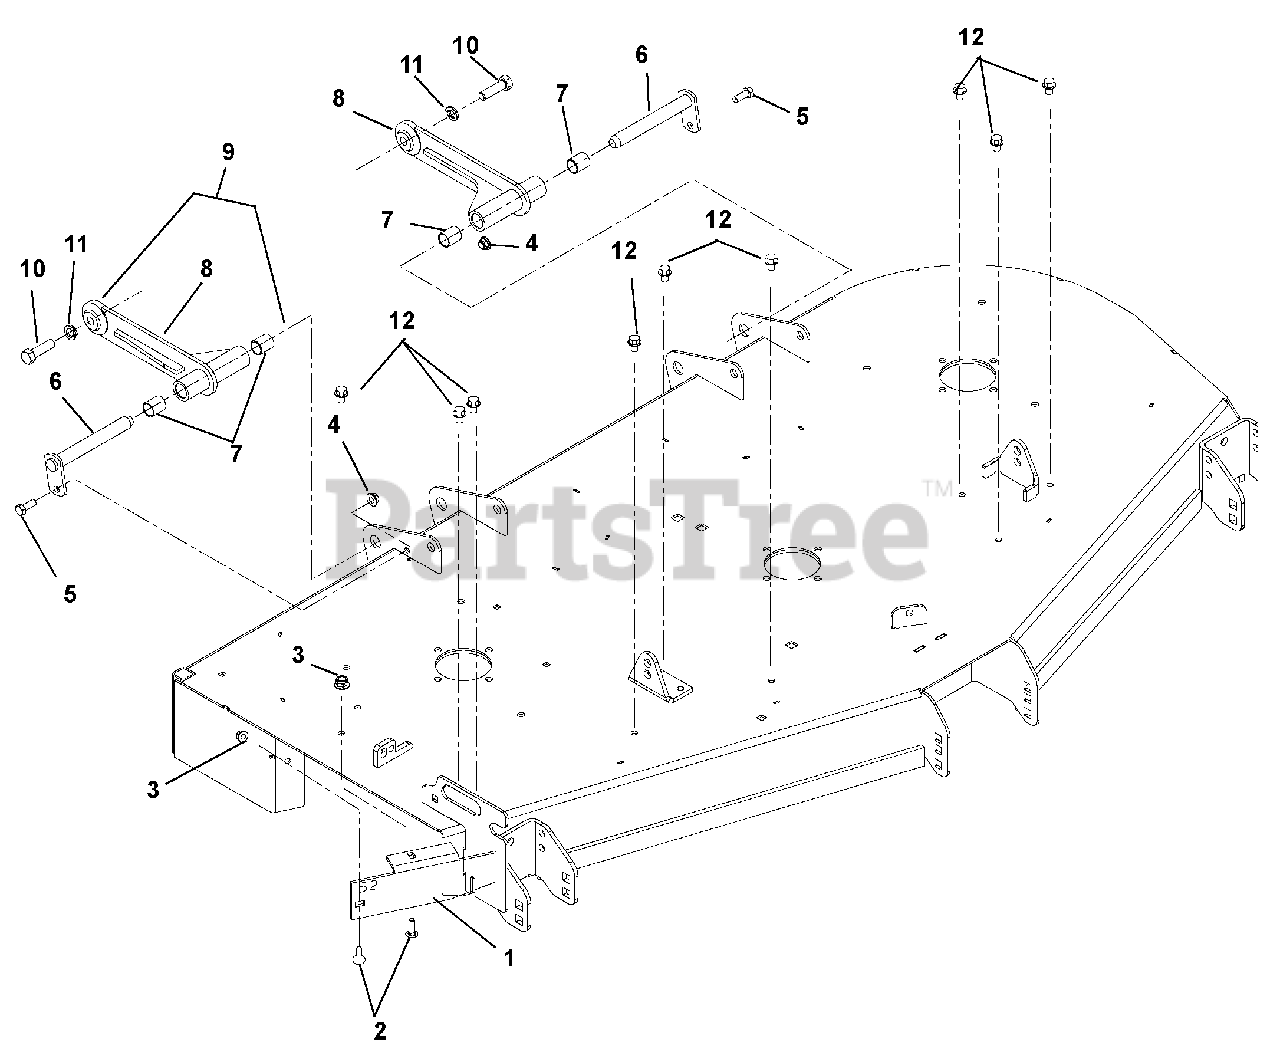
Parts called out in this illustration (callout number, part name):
1	Discharge Baffle, 44" & 48" (991082, 090, 098, 099, 107, 108)
1	Discharge Baffle, 60" (991084, 101, 110)
1	Discharge Baffle, 52" (991083, 100, 109)
2	Bolt, Round Head Square Neck .31-18 x 1.00 Grade 5
3	Nut, .31-18 Nyloc Flange
4	Nut, .38-16 Nyloc Flange
5	Bolt, Hex .38-16 x 1.00 Grade 5
6	Weldment, Mower Mounting Pin
7	Bearing, .75 x .875 x 1.00
8	Deck Pusher Arm Weldment
9	Assembly, Mower Mount Arm (Includes items 7 and 8)
10	Bolt, Hex .50-13 x 1.75 Grade 5 EP80
11	Washer, Locking .50 x .125 Regular
12	Screw, Tapping .38-16 x .50 Hex Washer Head
